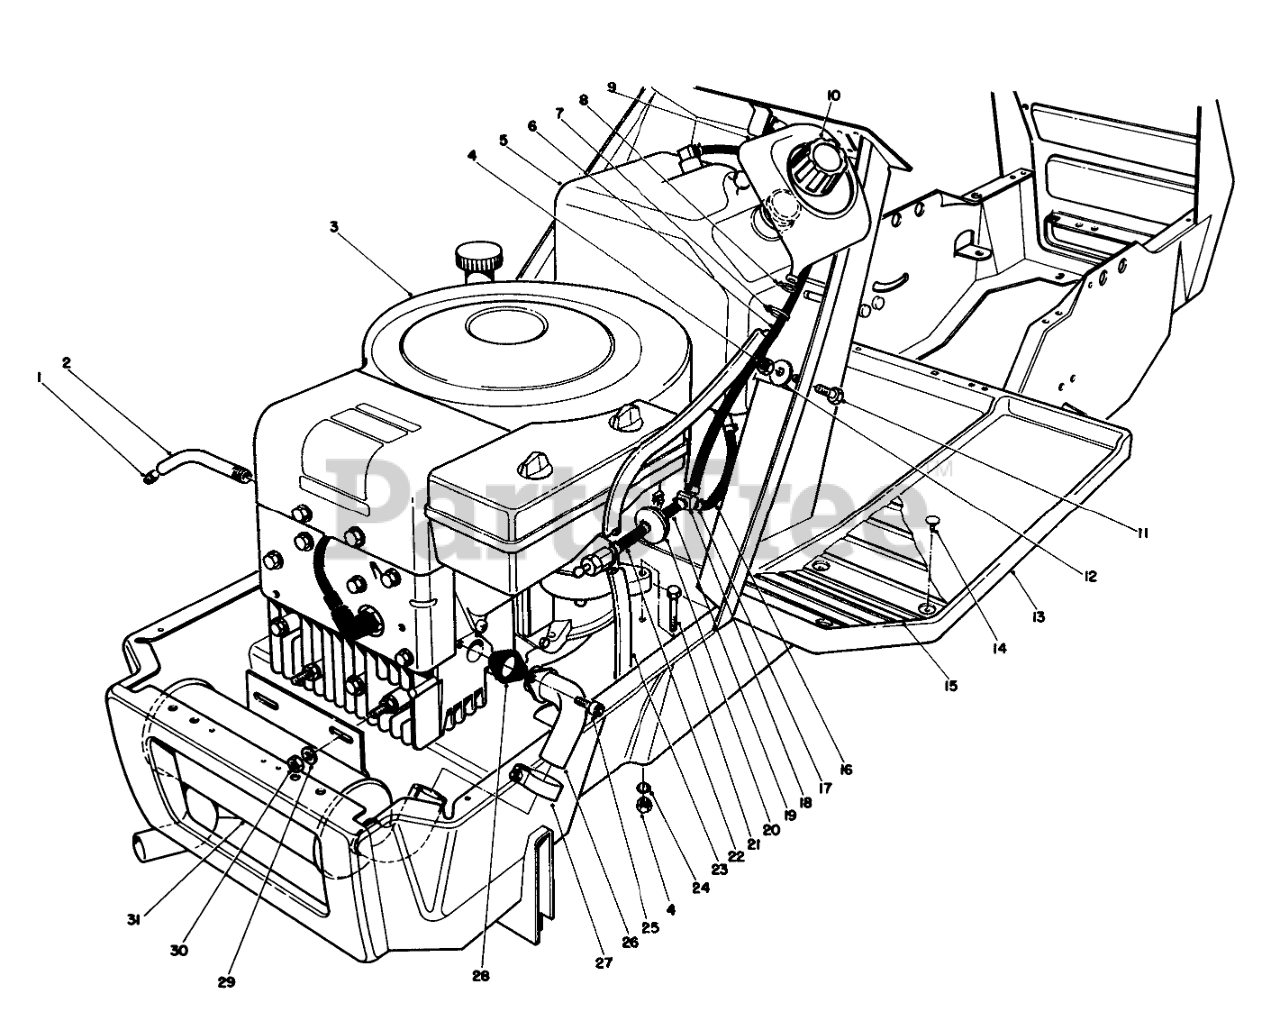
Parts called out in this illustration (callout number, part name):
1	PLUG-PIPE, SQH
2	OIL DRAIN TUBE
4	NUT-LOCK, NI
5	Gas Tank Assembly (Incl. Ref. #9, 10)
6	HOSE -RETURN
7	TIE-CABLE
8	HOSE CLAMP
9	Funnel-Overflow
10	GAS CAP ASM
11	SCREW-HH
12	WASHER
13	FRAME WA RO
14	FASTENER-PANEL
15	L/H FOOTREST TREAD
16	HOSE-FUEL
17	CLAMP-HOSE
18	Fitting-Barbed Y
19	GAS HOSE
20	Filter-Fuel
21	SCREW-HH
22	Hose-Gas
23	FUNNEL HOSE
24	WASHER-LOCK, INTERNAL
25	SCREW-HSH
26	12 HP EXHAUST PIPE WA
27	MUFFLER CLAMP
28	Gasket-Exhaust
29	WASHER-PLAIN
30	NUT-LOCK, CONE
31	Muffler
